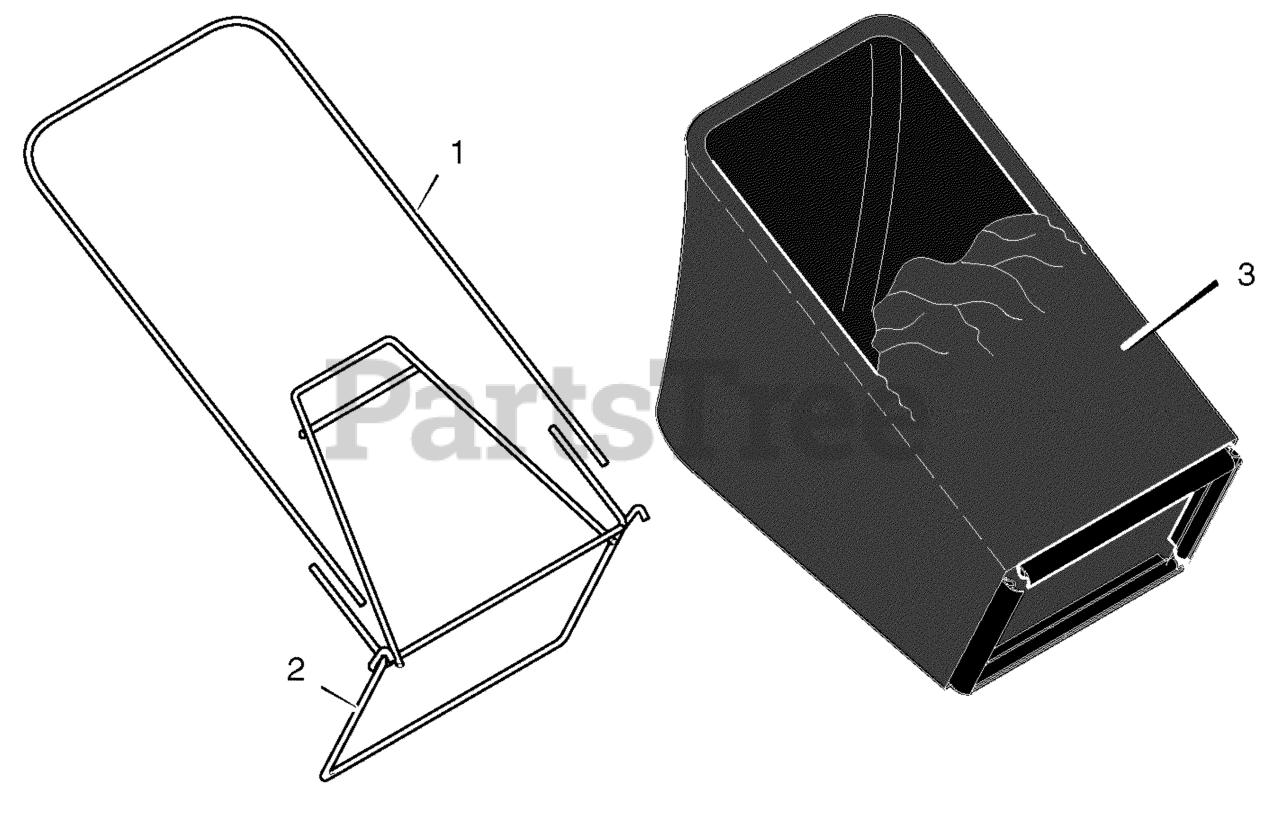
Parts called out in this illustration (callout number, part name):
1	Tube, Bag
2	Frame Assembly
3	Bag, Cloth -Black
